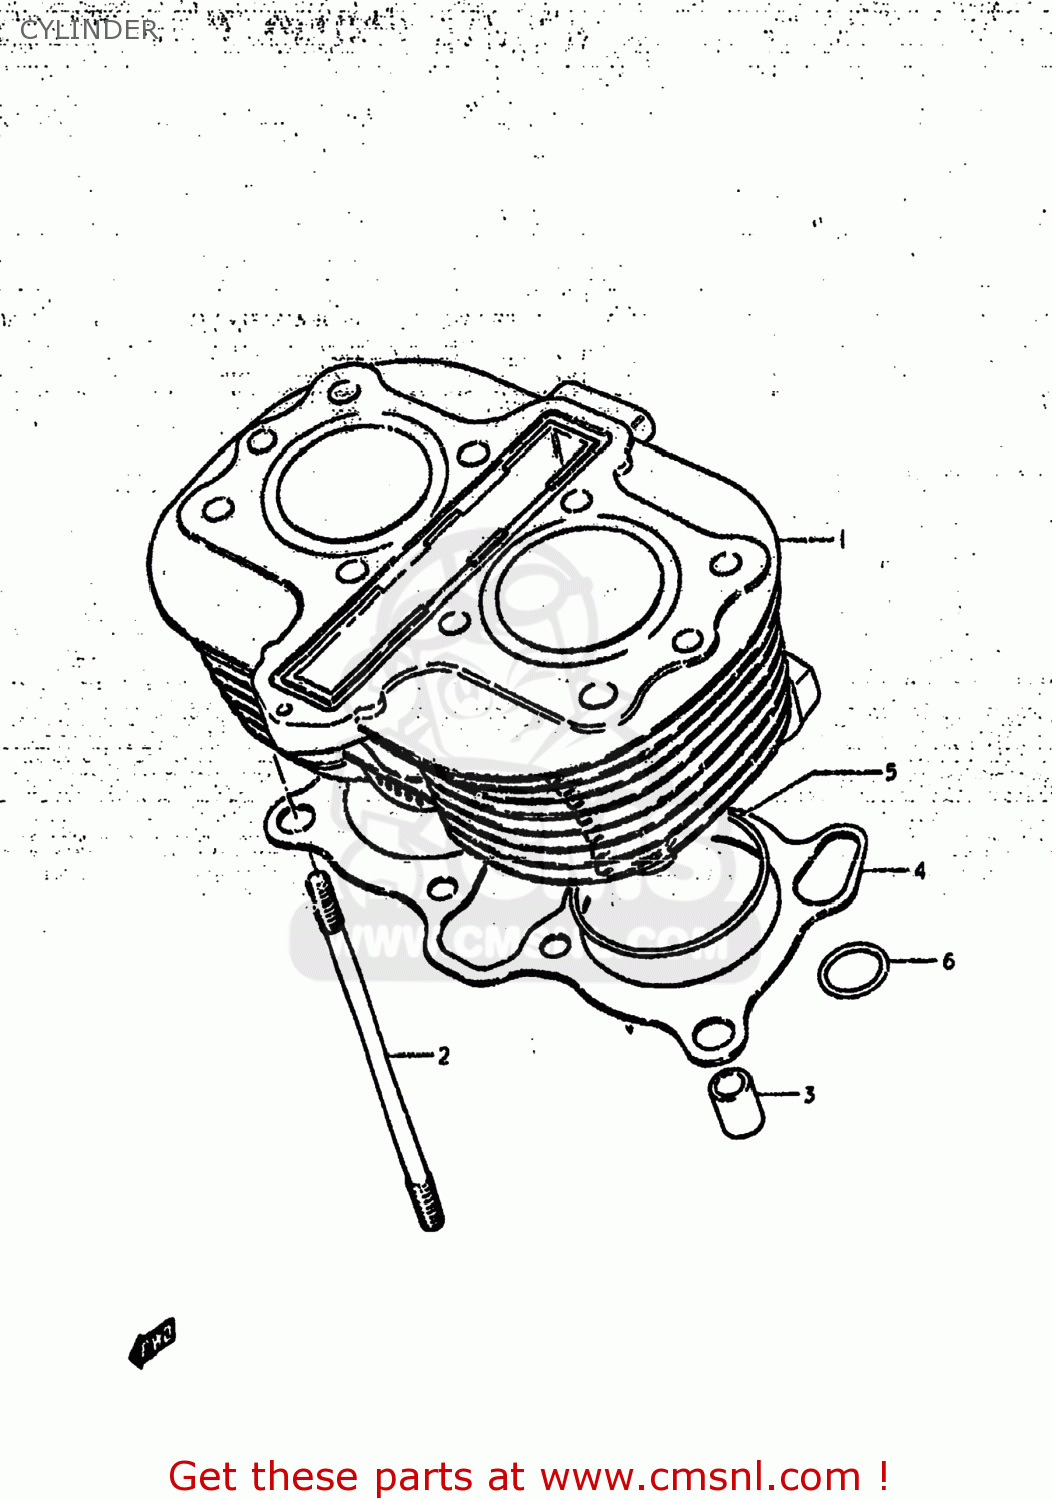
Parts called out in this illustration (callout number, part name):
1	CYLINDER
2	STUD
3	PIN
4	GASKET,CYLINDER (MCA)
5	O RING(D:2,ID:70)
6	O RING(D:3.05)
